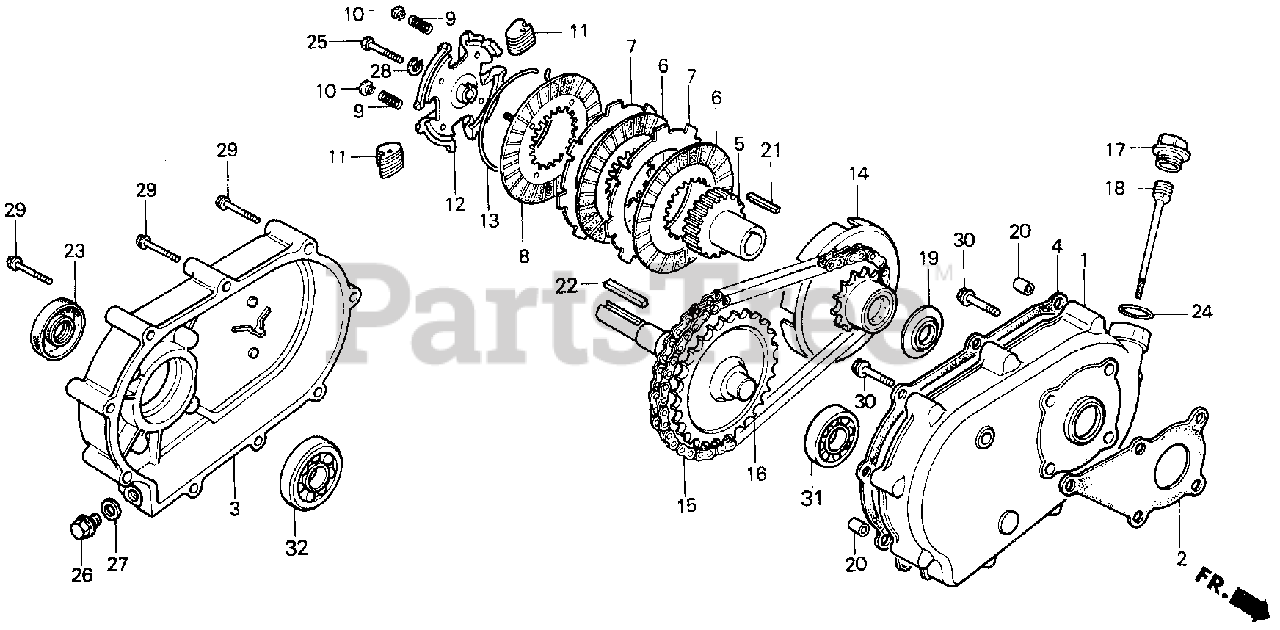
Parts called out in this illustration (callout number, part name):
1	CASE, REDUCTION
2	GASKET, REDUCTION CASE
3	COVER, REDUCTION
4	GASKET, REDUCTION COVER
4	GASKET, REDUCTION
5	CENTER, CLUTCH
6	DISK, CLUTCH FRICTION
7	PLATE, CLUTCH
8	PLATE, CLUTCH PRESSURE
9	SPRING, CLUTCH FREE
10	HOLDER, CLUTCH SPRING
11	WEIGHT, CLUTCH
12	HOLDER, CLUTCH WEIGHT
13	CENTER, CLUTCH WEIGHT
14	SPROCKET, DRIVE
15	CHAIN, DRIVE (RK428SH-36LE)
16	SHAFT, P.T.O. (28T)
17	CAP, REDUCTION OIL
18	DIPSTICK, OIL
19	WASHER, THRUST (20MM)
20	PIN, DOWEL (8X10)
21	KEY (5MM)
22	KEY (7X7X33)
23	OIL SEAL (PJ30507)
24	O-RING (26X2.7)
25	BOLT, HEX. (8X36)
25	BOLT, HEX. (8X35)
26	BOLT, DRAIN PLUG (12MM)
27	WASHER, DRAIN PLUG (12MM)
28	WASHER, SPRING (8MM)
29	BOLT, FLANGE (6X55)
30	BOLT, FLANGE (8X22)
31	BEARING, RADIAL BALL (6205)
32	BEARING, RADIAL BALL (6206)
